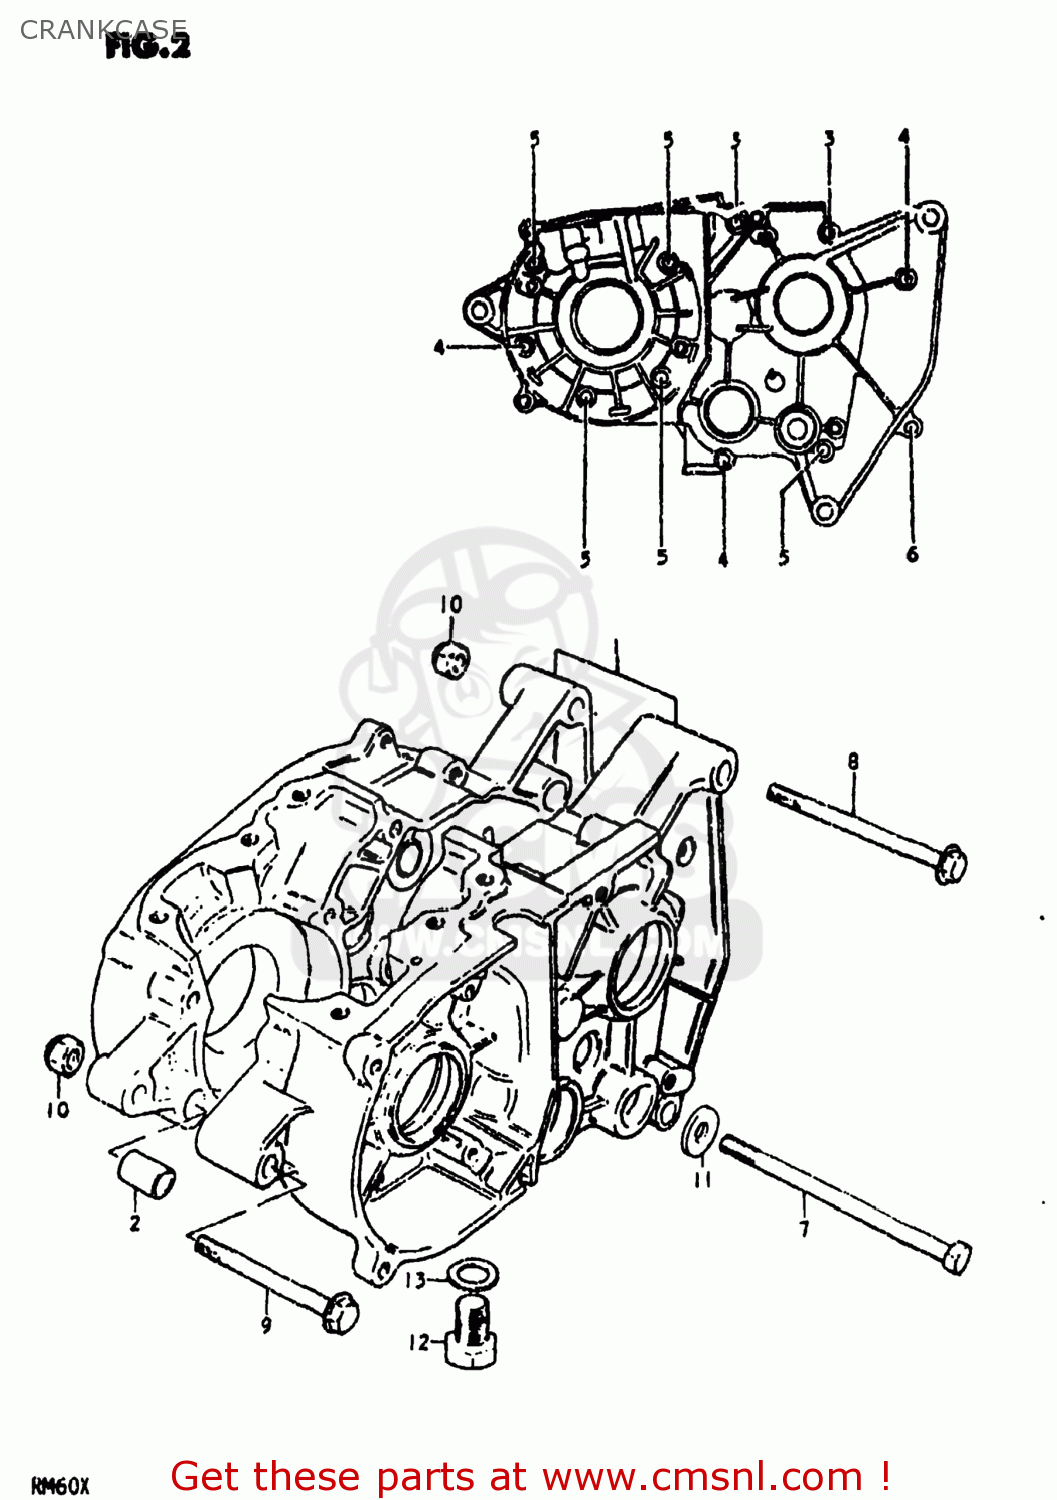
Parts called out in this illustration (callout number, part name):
1	CRANKCASE SET
2	PIN
3	CROSS SCREW (6 X 75)
4	SCREW
5	SCREW (6X35)
6	SCREW
7	BOLT 8X115
8	BOLT
9	BOLT 8X75
10	NUT
11	WASHER
12	BOLT 10X20
13	GASKET(10X14X3.6) (NAS)
